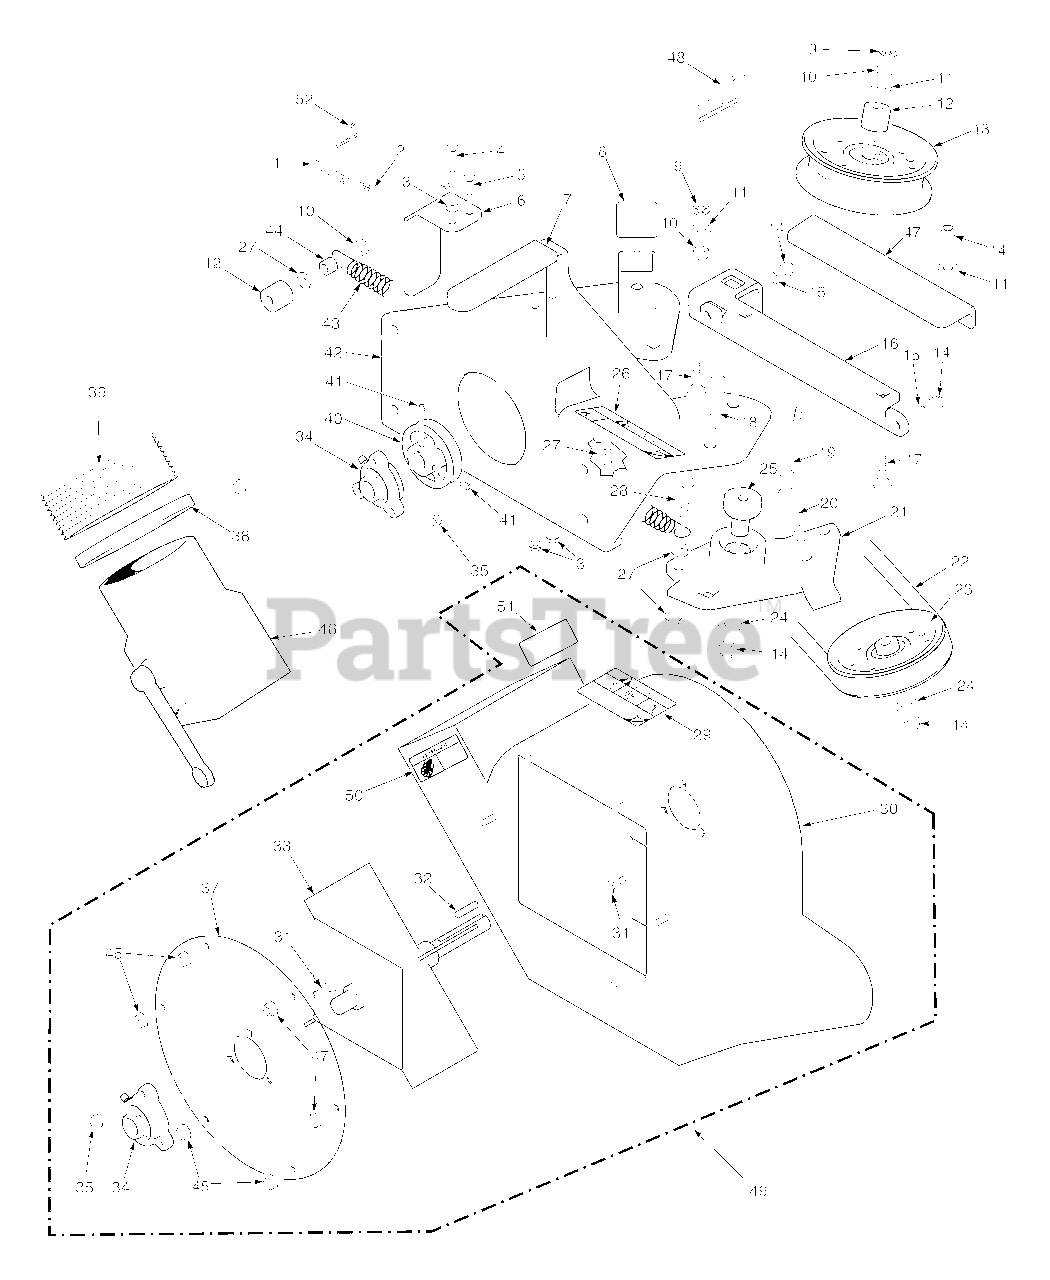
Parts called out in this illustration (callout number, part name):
1	Pin, Ring 2-1/4" Long
2	Lanyard, Deck Height Pin
3	Nut, Serr. Flange 1/4-20
4	Bolt, Hex Head 1/4-20 x 1-1/4"
5	Bolt, Hex Head 1/4-20 x 3/4"
6	Belt Cover, Rear
7	Grip, Blower Lever
8	Cap, Square
9	Nut, Push On 3/8 Thread
10	Lock Nut, 3/8-16
11	Flatwasher, 3/8-.391 x .938 x .105
12	Spacer
13	Pulley, Idler 4" Dia.
14	Nut, Elastic Stop 3/8-16
15	Lockwasher, 3/8-16
16	Plate, Catch Mounting
17	Bolt, Carr. 3/8-16 x 1-1/2"
18	Bolt, Hex Head 3/8-16 x 2-1/4"
19	Bolt, Hex Head 3/8-16 x 3-1/2"
20	Bolt, Hex Head 3/8-16 x 1-3/4"
21	Idler Arm Assembly, GC-STT 61"
22	Belt, GC-STT 61"
23	Pulley, 4" O.D., GC-STT
24	Washer, 3/8 Hardened
25	Pivot, Idler - 61" & 72"
26	Decal, Belt Cover
27	Nut, Serr. Flange 3/8-16
28	Bolt, Hex Head 3/8-16 x 1-1/2 Gr. 8
29	Decal, Danger
30	Blower Housing w/Decals
31	Bolt, Carr. 5/16-18 x 3/4" Gr. 5
32	Key, 1/4 x 1/4 x 1-1/2"
33	Fan Weldment
34	Bearing Assembly
35	Nut, Serr. Flange 5/16-18
36	Flatwasher, 5/16-.344 x .688 x .065
37	Cover, Blower Housing
38	Clamp, 8-5/8" Max Dia.
39	Hose, 8.00" Dia. x 56.00" Long
40	Pulley, 4-3/4" O.D. - 1" Bore
41	Set Screw, 5/16-18 x 3/8"
42	Frame, Blower Mount - 61"
43	Spring, Main Drive
44	Spacer
45	Nut, Serr. Flange 5/16-18
46	Adapter w/Strap
47	Plate, Blower Catch
48	Hair Pin Cotter, .243 x 4"
49	Blower Housing Assembly, GC-STT
50	Decal, Rotating Blower
51	Decal, Blower
